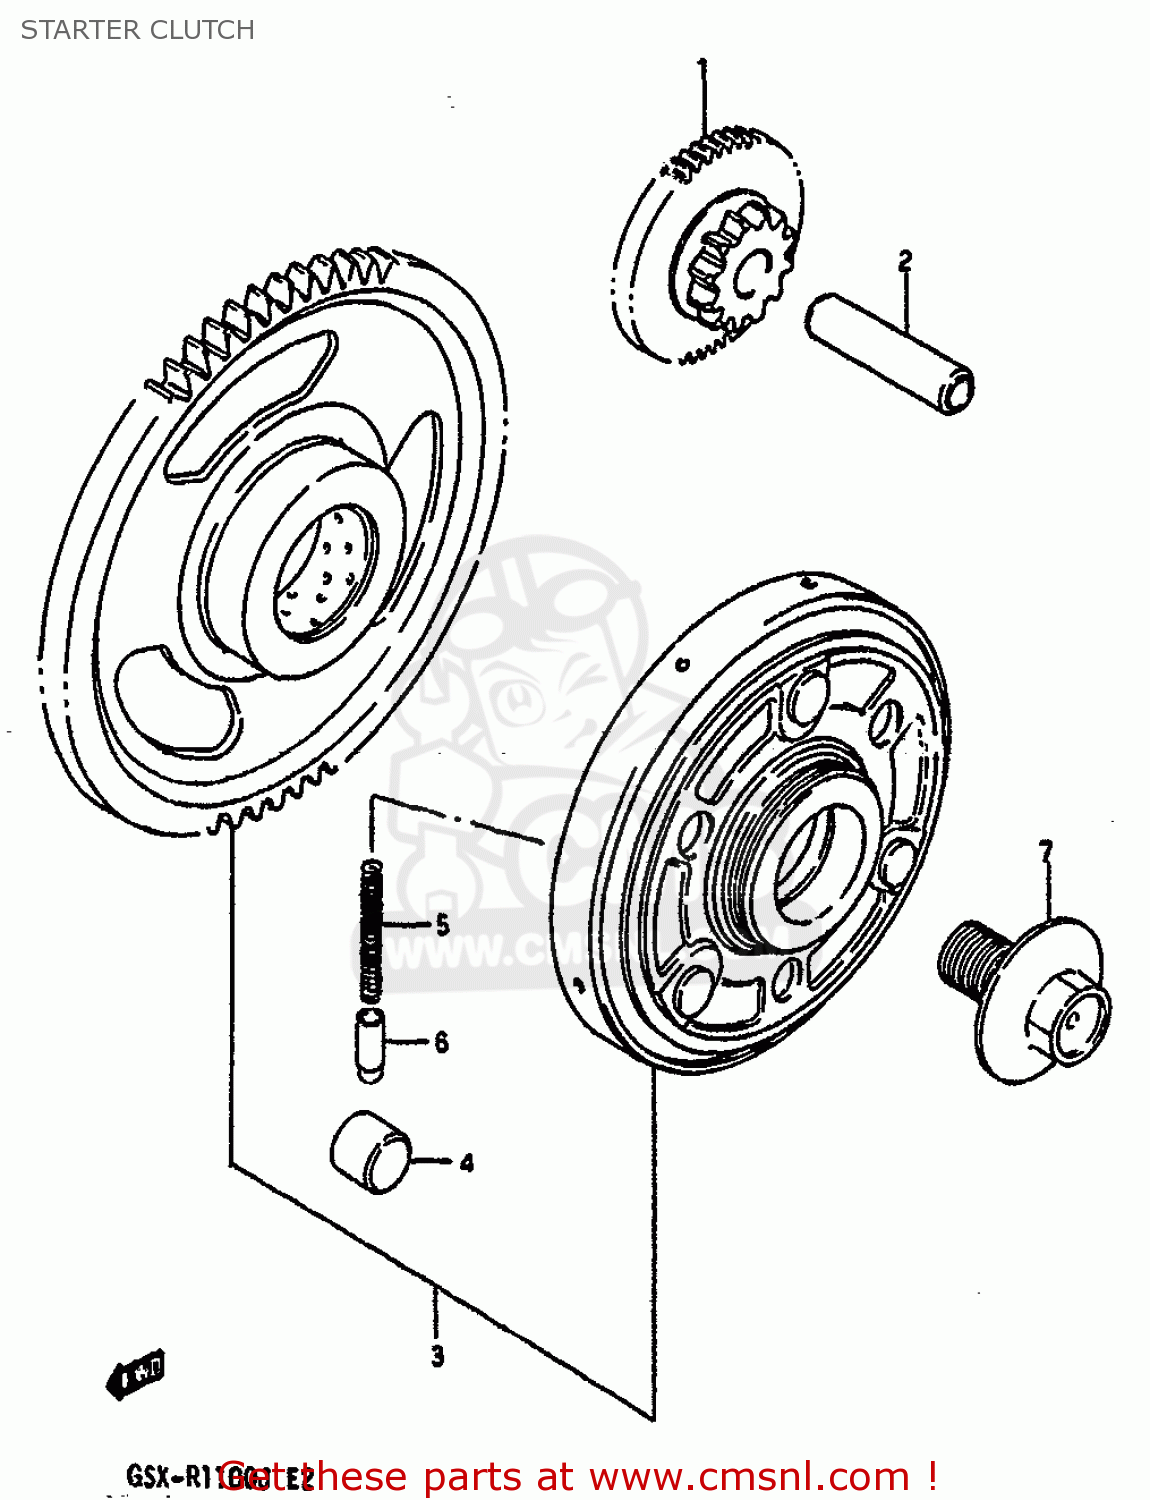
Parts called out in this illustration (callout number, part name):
1	GEAR,STARTER IDLE(NT:12,53)
2	PIN(7X11X42)
3	CLUTCH SET,STARTER
4	ROLLER(15X13)
5	SPRING
6	PIECE,PUSH
7	BOLT(14X21)
